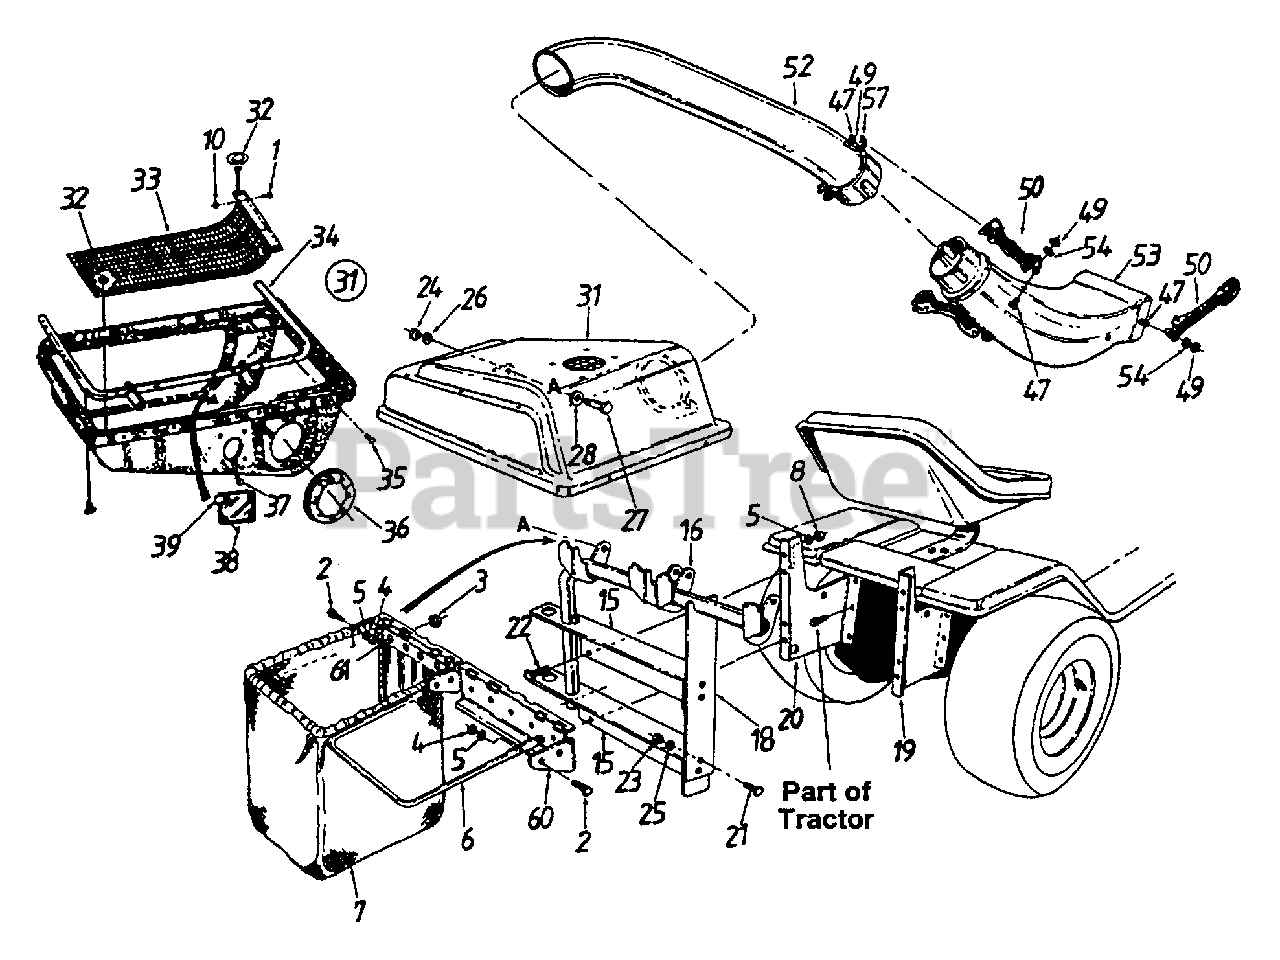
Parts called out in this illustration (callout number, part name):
1	Pop Rivet .188 Dia.
2	Hex Bolt 1/4-28 x .88"
3	Hex Sems Nut #10-24 Thd.
4	Hex Nut 1/4-28 Thd.
5	L-Wash. 1/4" I.D.
7	Grass Catcher Bag
8	Hex Nut 1/4-20 Thd.
10	Flat Wash. 1/4" I.D.
22	Hex Bolt 1/4-20 x .62" Lg.-Grade 5
23	Hex Nut 5/16-18 Thd.
24	Hex Nut 3/8-16 Thd.
25	L-Wash. 5/16" I.D.
26	L-Wash. 3/8" I.D.
27	Shld. Bolt 3/8-16 x .50" Dia.
28	Bell-Wash. .505" I.D. x 1.0" O.D.
31	Grass Catcher Cover Ass'y. (063)
32	Twist Fastener
35	Hex AB-Tap Scr. 1/4 x .62"
36	Seal-7" (063)
37	Truss B-Tap Scr. #10 x .5" Lg.
38	Plastic Plate
39	Speed Nut
47	Hex Bolt 1/4-20 x .625"
49	Hex Ins. L-Nut 1/4-20 Thd.
50	Retainer Strap Ass'y.
52	Catcher Tube (063)
53	Discharge Chute (063)
54	L-Wash. .27" I.D.
57	Retainer Hook Brkt.
61	Truss Mach. Scr. #10-24 x .5"
